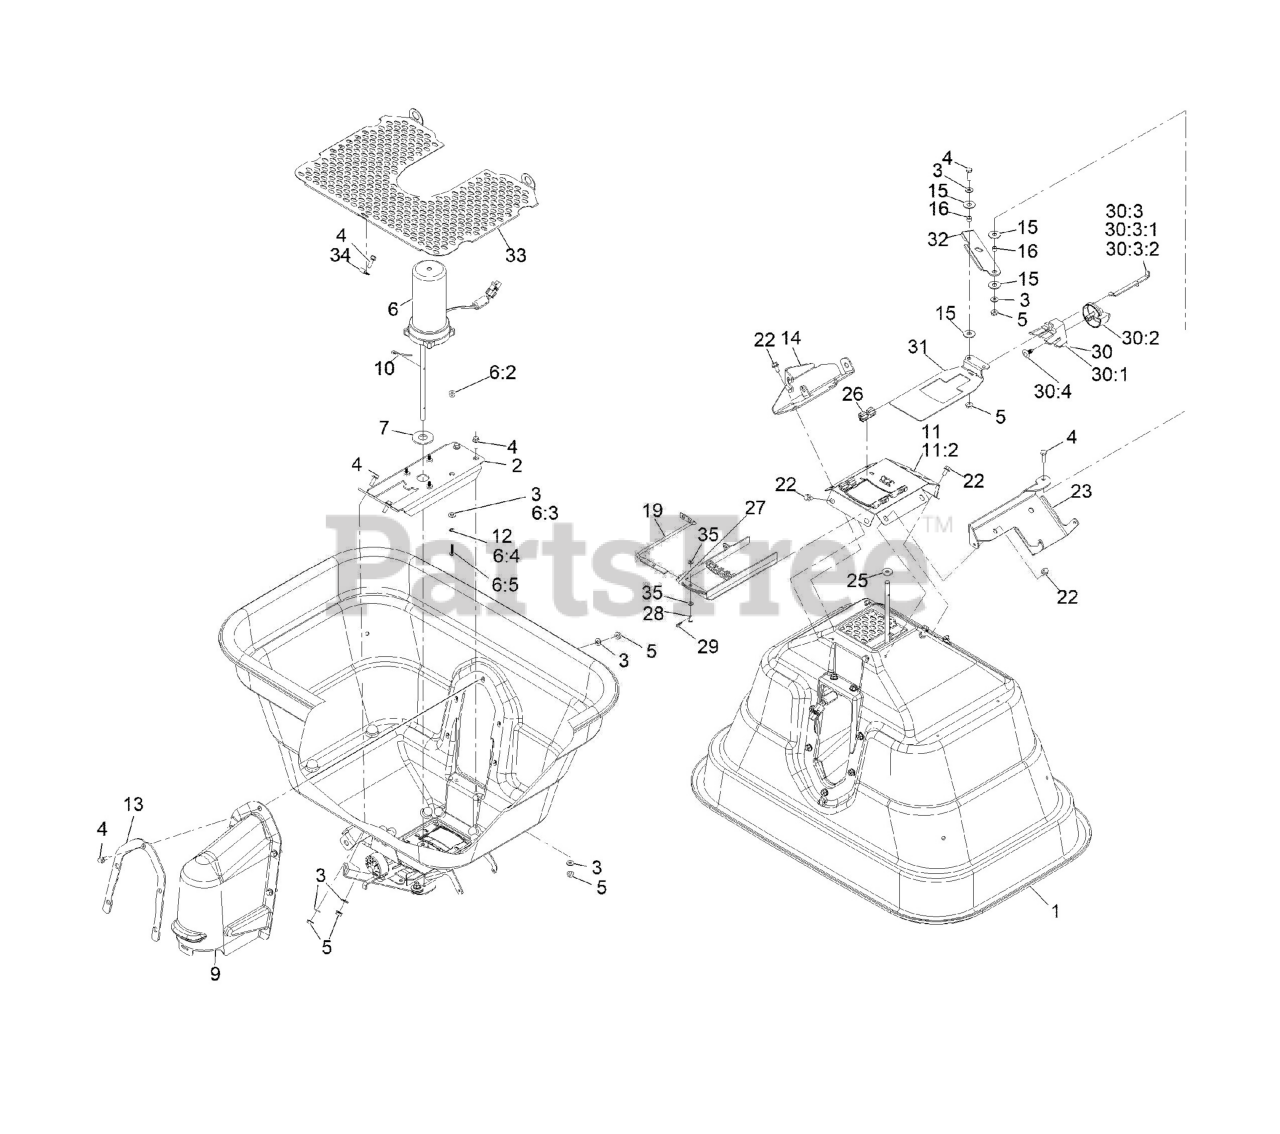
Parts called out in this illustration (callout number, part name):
1	Hopper-Spreader, 175 Lb
2	BRACKET-MOUNT, MOTOR
3	WASHER-FLAT
4	SCREW-HH
6	SPREADER MOTOR ASM
6:2	SPACER-FLANGED
6:3	WASHER-FLAT
6:4	WASHER-LOCK, INT
6:5	SCREW-SHWH
9	COVER-MOTOR
10	WIRE-AGITATOR
11	HOPPER PLATE W/ BEARING ASM
11:2	HOPPER BOTTOM BEARING
12	WASHER-LOCK, INT
13	FLANGE-COVER, MOTOR
14	BRACKET-HOPPER, GATE CONT
19	ROD-CONTROL, DIFFUSER
22	SCREW-HHF
23	BRACKET-LEVER, HOPPER GATE
25	WASHER-FELT
26	GUIDE-RATE, GATE
27	DIFFUSER
28	PIN-CLEVIS
29	PIN-COTTER, HAIR
30	RATE DIAL ASM
30:1	MOUNT-DIAL
30:3	Rate Gate Link ASM
30:3:1	LINK-GATE, RATE
30:3:2	SCREW-SHOULDER, SLOTTED
30:4	Footpad Fastener
31	RATE GATE
32	LEVER-GATE
33	SCREEN-HOPPER, LARGE HOLE
33	SCREEN-HOPPER, MEDIUM HOL
33	SCREEN-HOPPER, SMALL HOLE
34	CLAMP-LOOP
35	WASHER-FLAT
